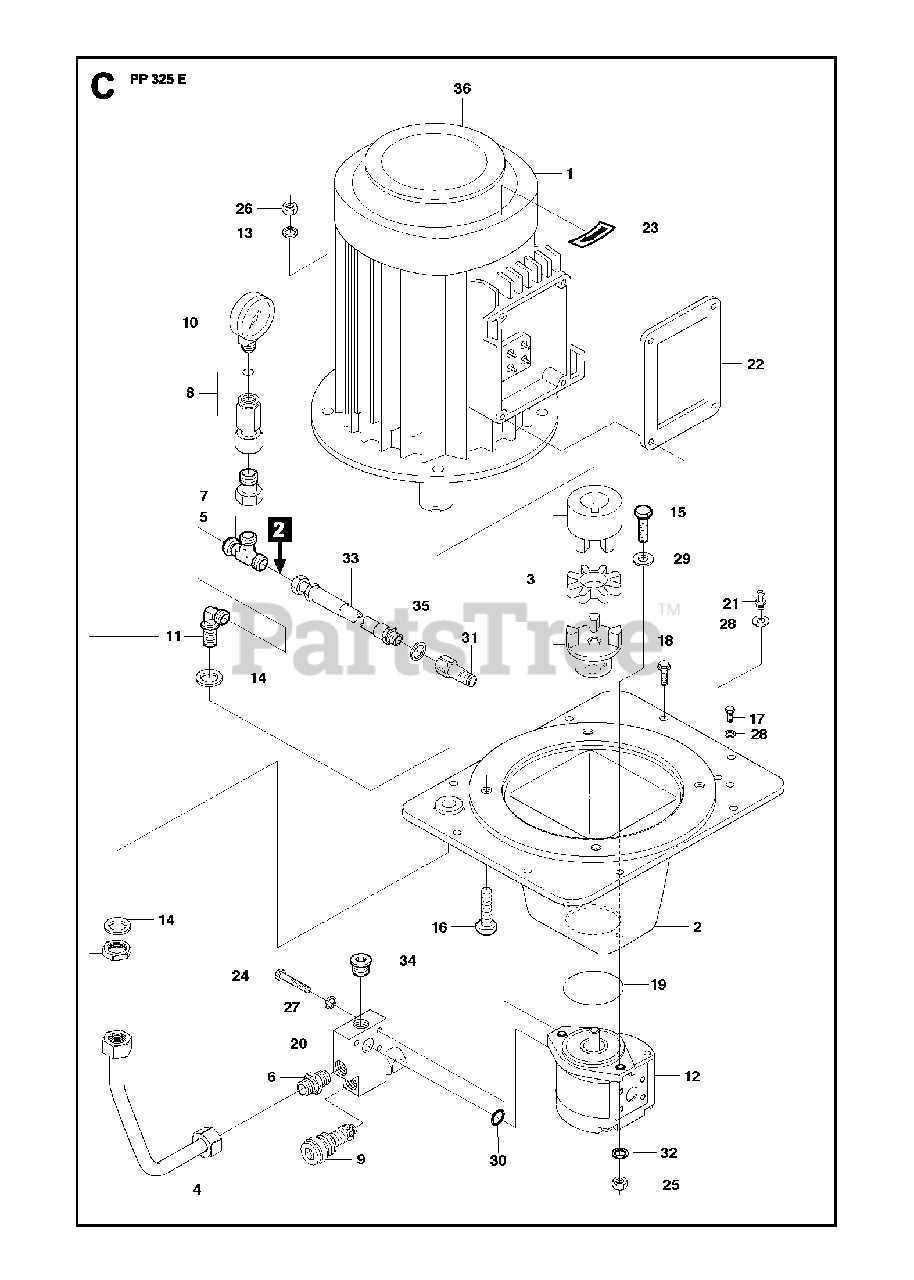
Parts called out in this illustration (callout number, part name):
1	ELECTRIC BOX400Ð440 V
1	ELECTRIC BOX230 V
29	SEALING WASHER
